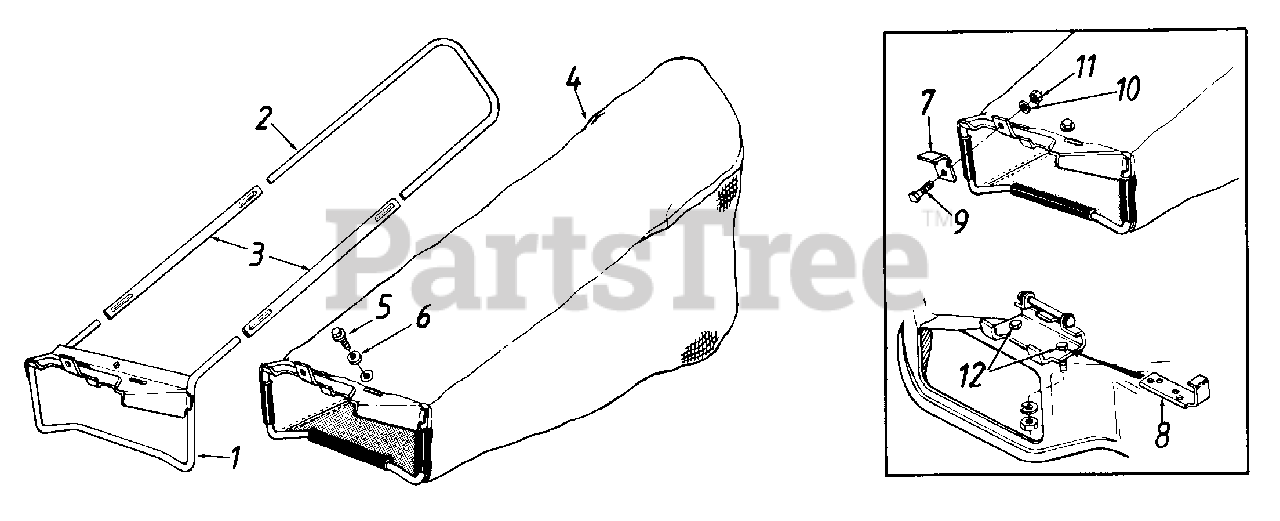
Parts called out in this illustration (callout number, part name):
1	Frame-Lower Ass'y.
4	Grass Bag
5	Hex Wash Hd. TT-Tap Scr. 1/4-20 x 5" Lg.
6	Bell-Wash. 1/4" I.D.
7	Deflector Stop
8	Support Plate
9	Hex Bolt 1/4-20 x .5" Lg.
10	L-Wash. 1/4" I.D.
11	Hex Nut 1/4-20 Thd.
12	Hex Bolt 1/4-20 x .62" Lg.
